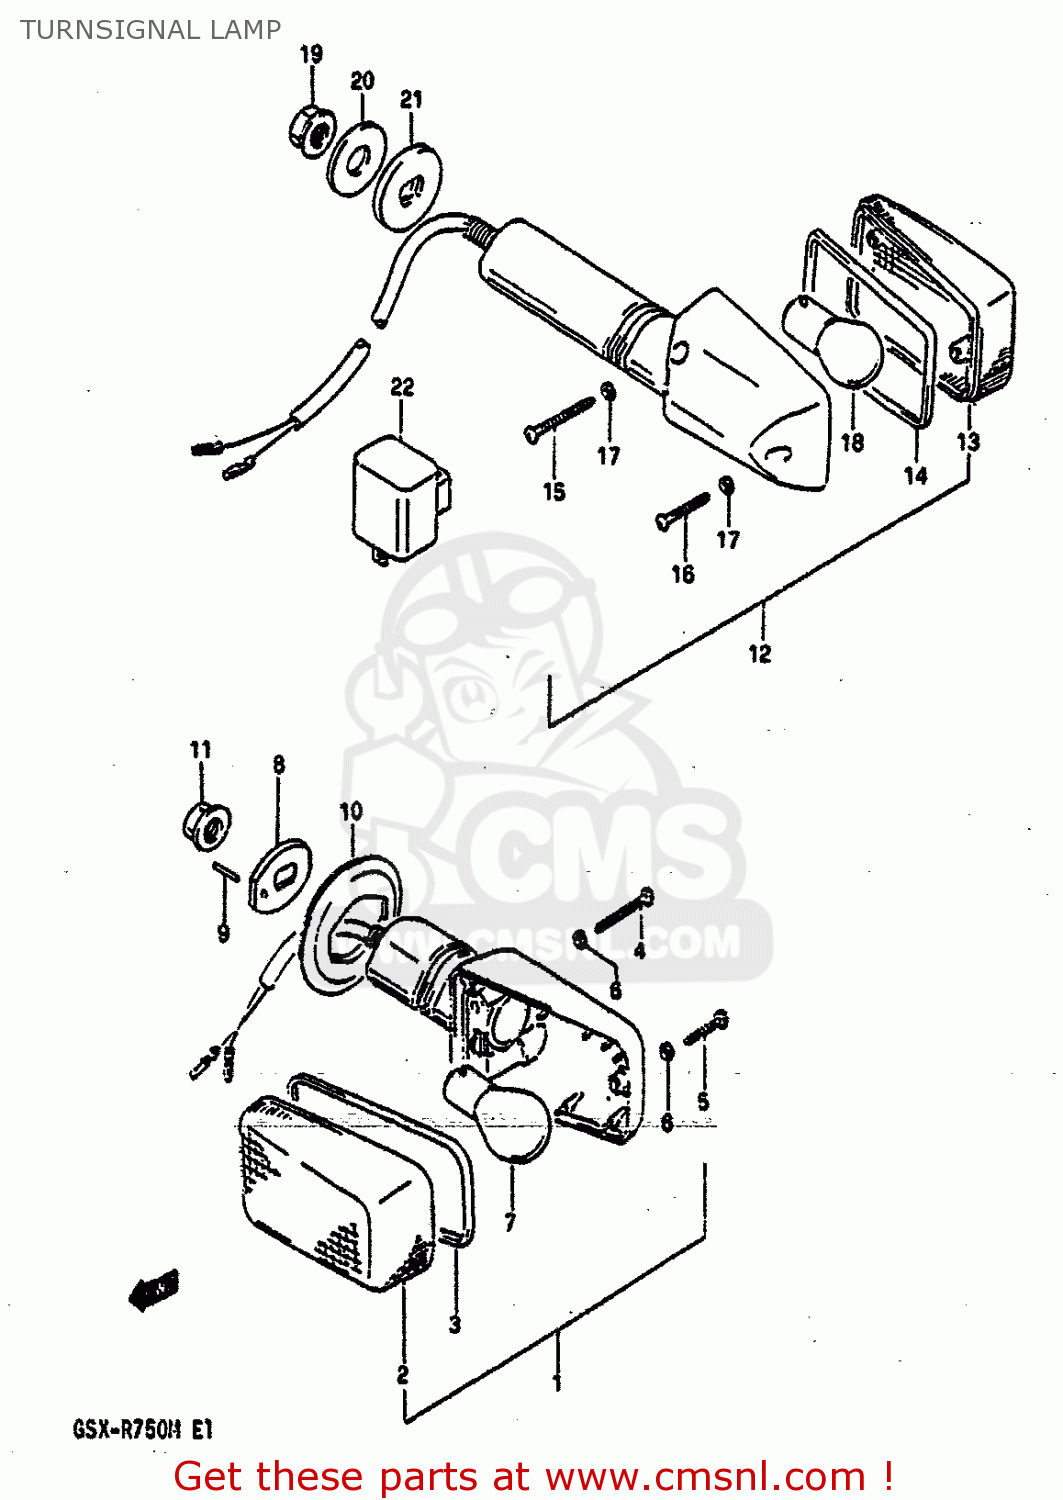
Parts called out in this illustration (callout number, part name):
1	LAMP ASSY,FRONT TURNSIGNAL
2	LENS
3	GASKET (NAS)
4	SCREW(3X30)
5	SCREW
6	GASKET (NAS)
7	BULB(12V21W)
8	SPACER,FRONT TURN
9	PIN(4X9)
10	GROMMET
11	NUT
12	LAMP ASSY,RR TURNSIGNAL
13	LENS
14	GASKET (NAS)
15	SCREW(3X30)
16	SCREW
17	GASKET (NAS)
18	BULB(12V21W)
19	NUT
20	WASHER(10.5X30X3.2)
21	SPACER,RR TURNSIGNAL
22	RELAY ASSY,TUR
